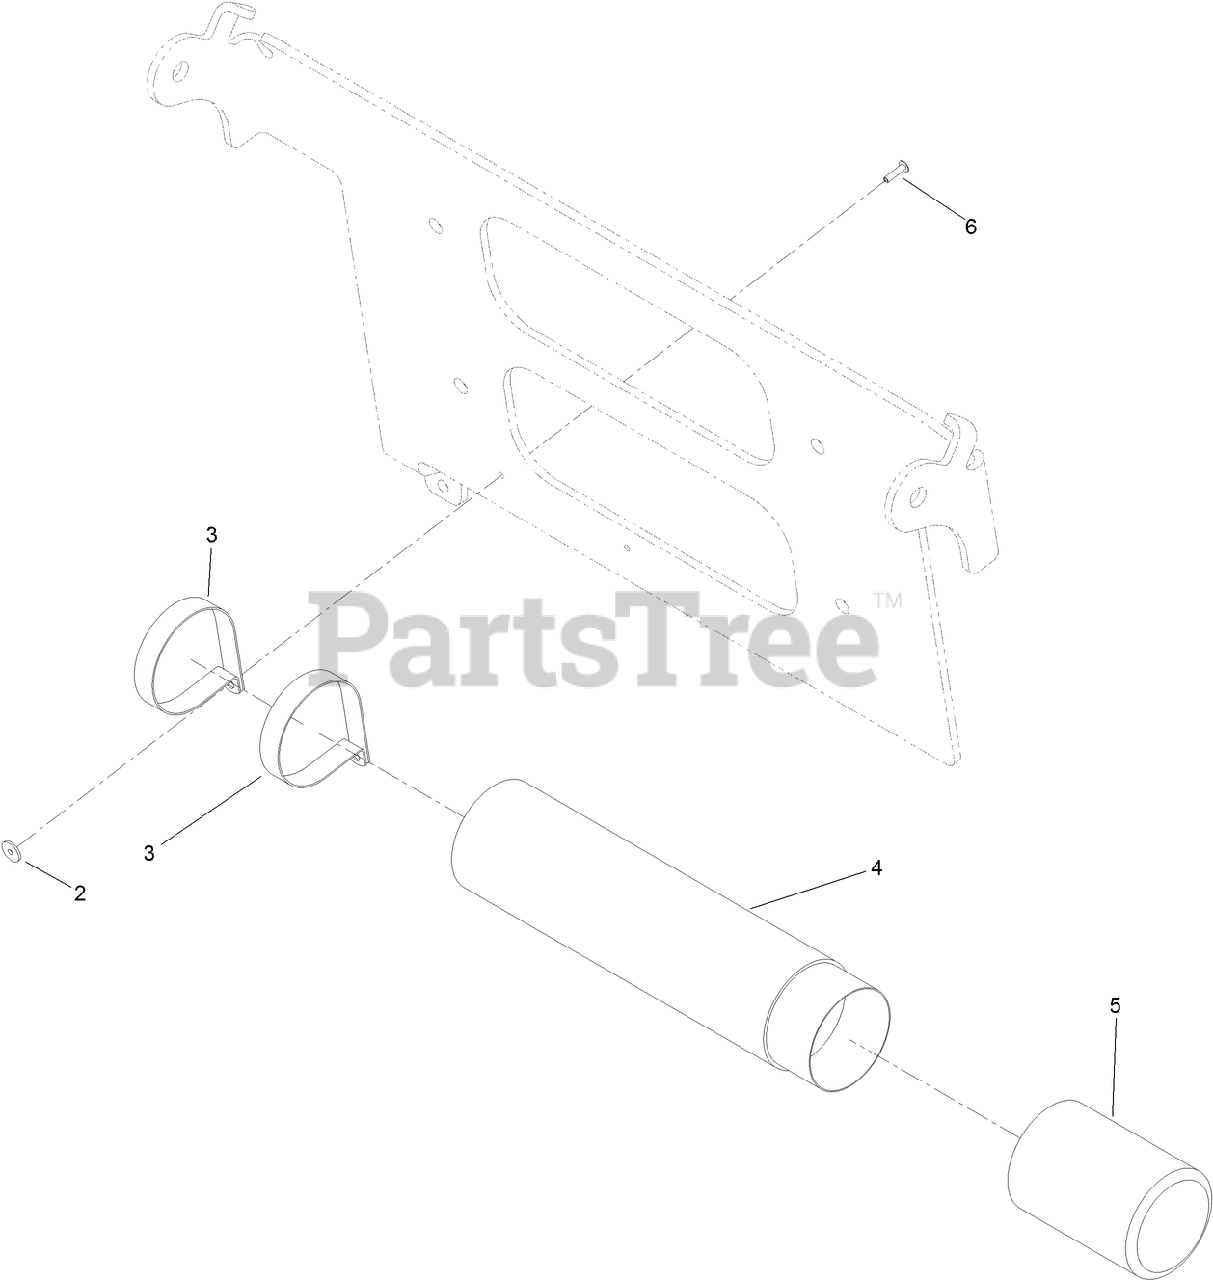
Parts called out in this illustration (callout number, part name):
2	WASHER-BACK
3	CLAMP-R
4	TUBE-MANUAL
5	CAP-HOUSING
6	RIVET-POP
